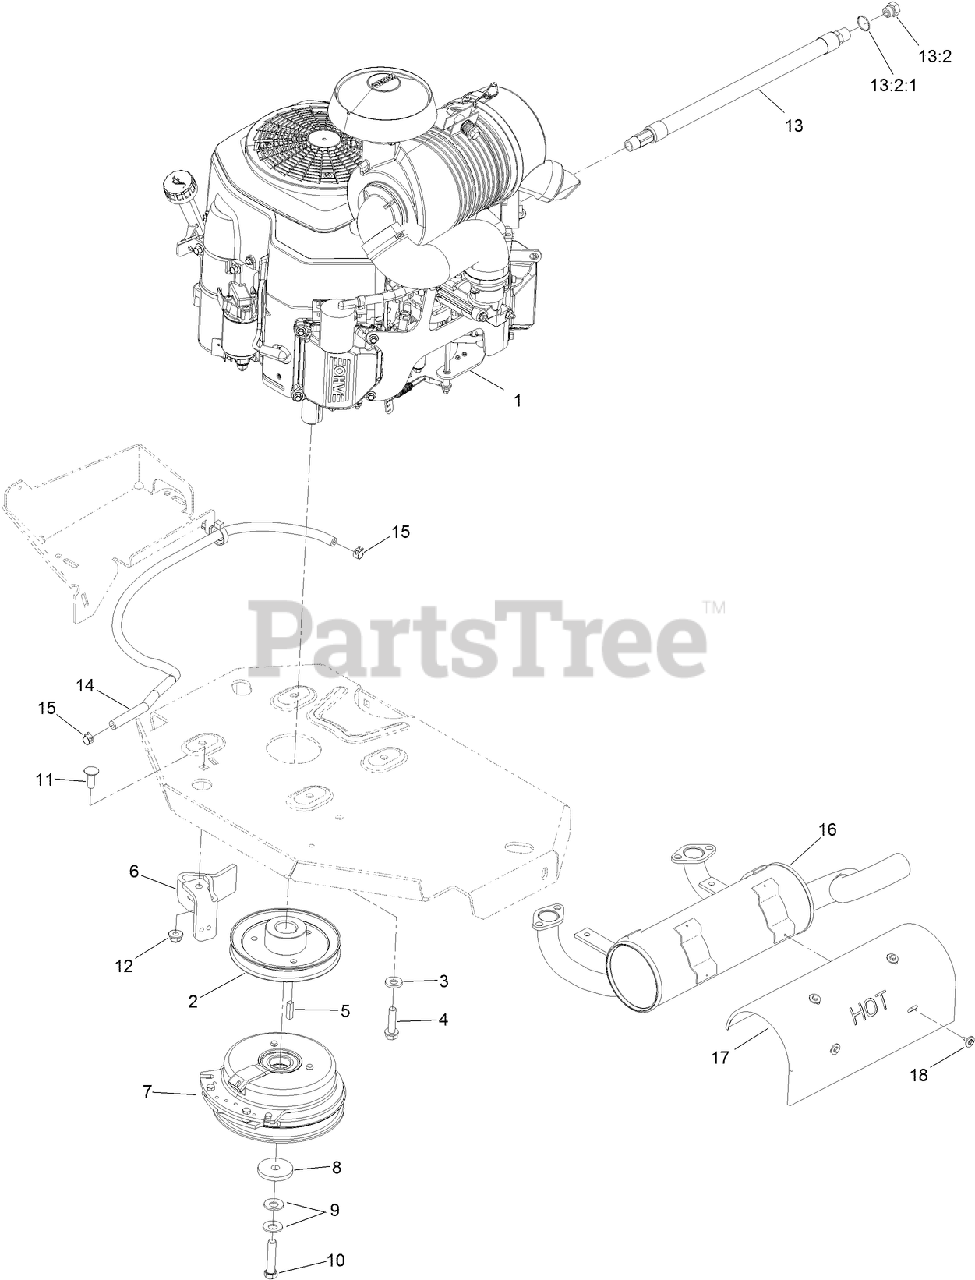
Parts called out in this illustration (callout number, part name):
2	SHEAVE
3	WASHER-BELLEVILLE
4	SCREW-HWH
6	CLUTCH-ANCHOR
7	CLUTCH KIT
8	WASHER-CLUTCH
9	WASHER-SPRING
10	SCREW-HH W/LOCTITE
11	SCREW-CARR
12	NUT-HF, NI
13	OIL DRAIN HOSE ASM
13:2	PLUG-HH
13:2:1	O-RING
14	HOSE-FUEL
15	CLAMP-HOSE
16	MUFFLER
17	GUARD-MUFFLER
18	SCREW-HH, THREAD FORMING
